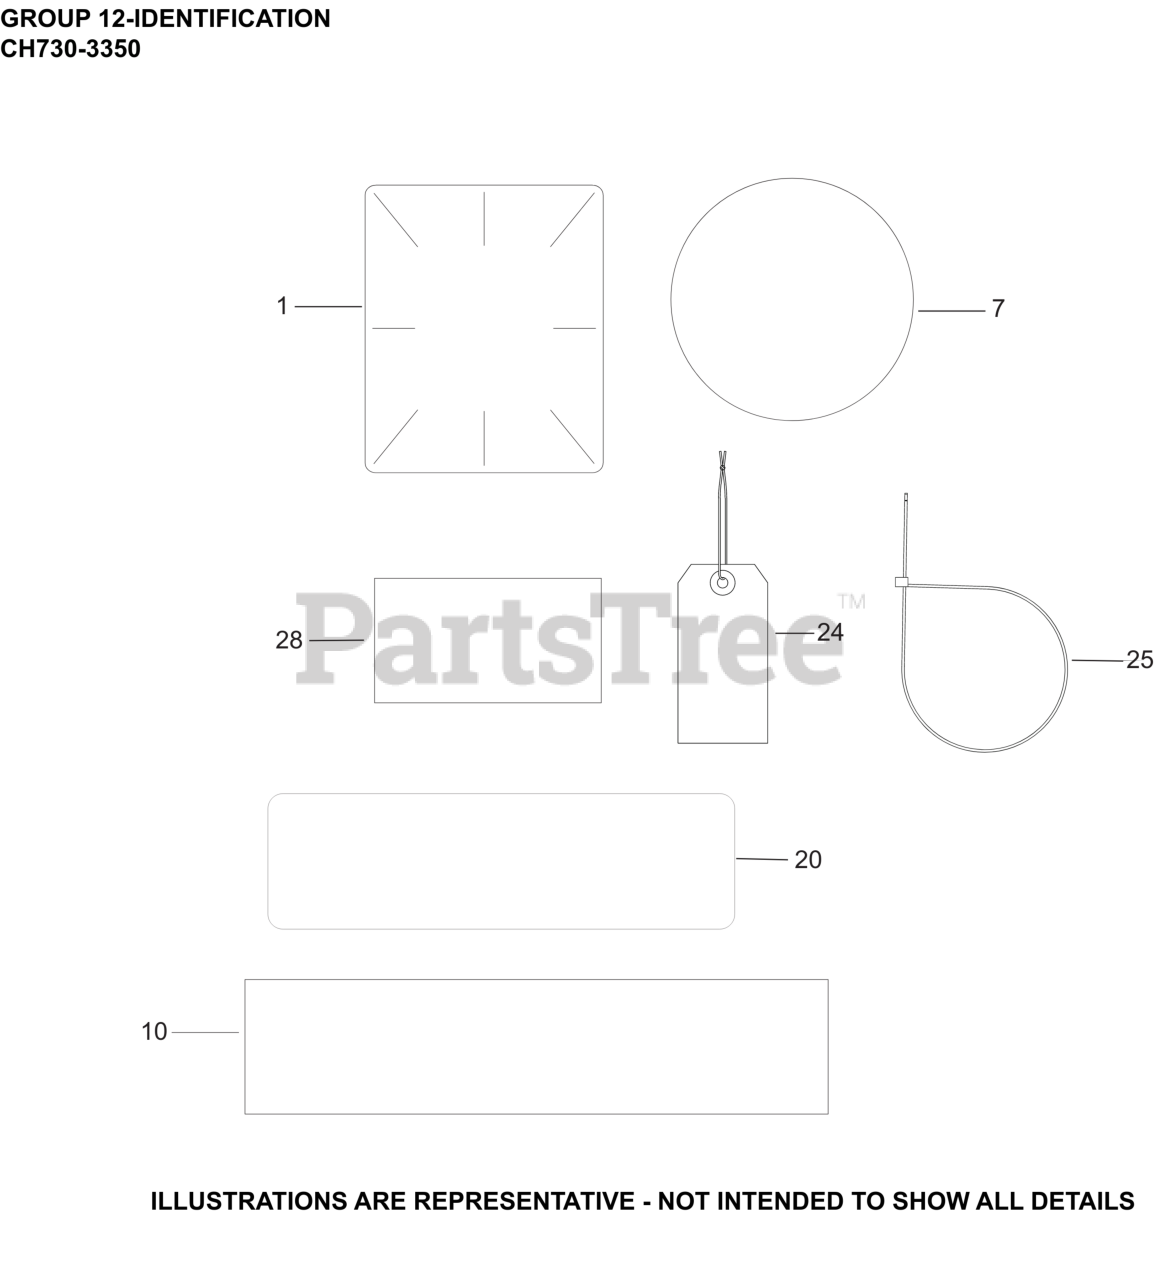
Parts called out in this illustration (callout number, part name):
1	LABEL, CLEAR LAMINATION
7	LABEL, GRASS SCREEN
10	DECAL, STOPPING INSTRUCTION
20	DECAL LPAC, 23.5 HP/725cc/CH730
24	TAG, HANG (OIL SENTRY)
28	DECAL, USA
